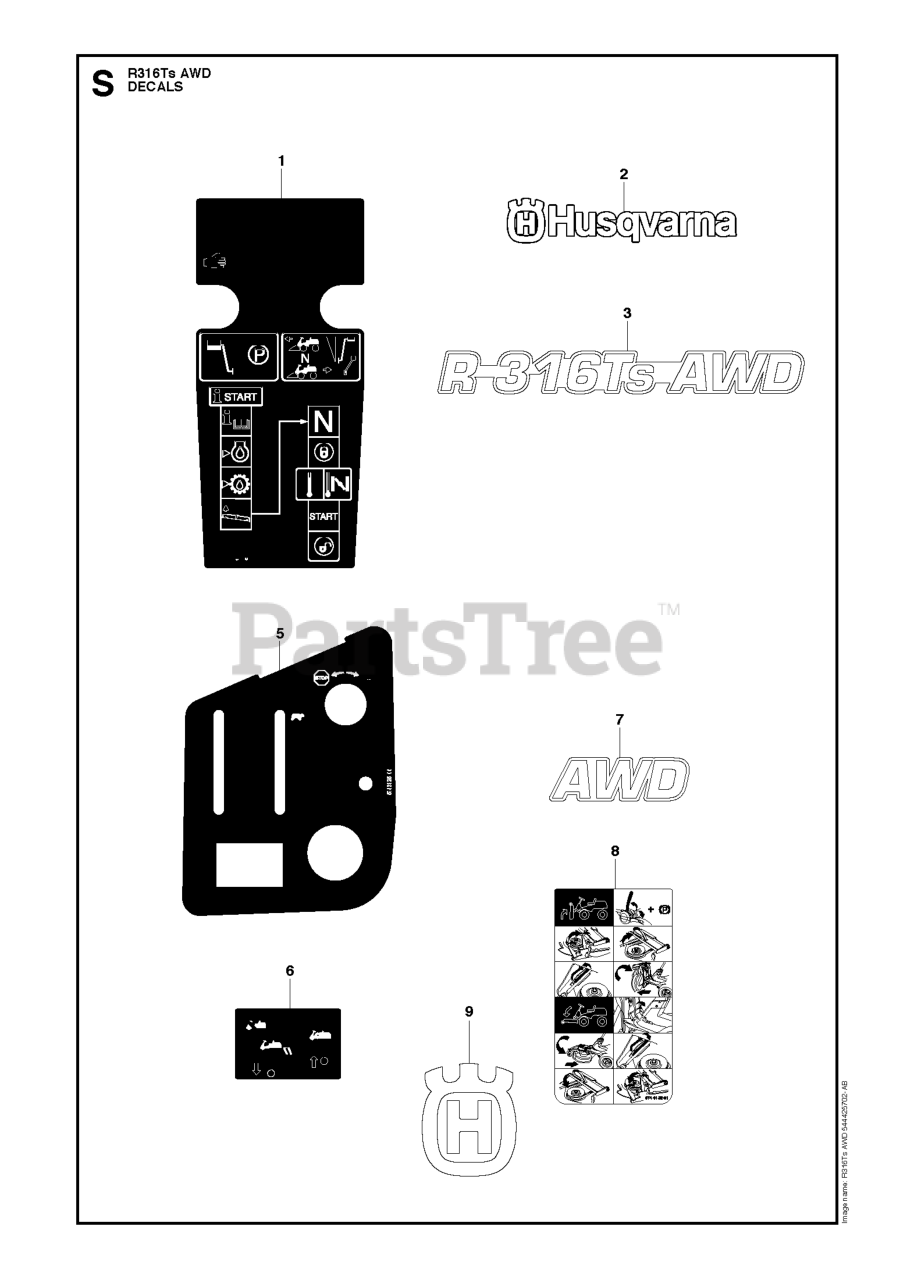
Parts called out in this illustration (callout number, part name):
1	CRANKCASE-C
2	GASKET CASE
5	SEAL
7	BOLT
8	COVER, CASE
9	BOLT 08
10	PISTON
16	CRANKSHAFT C
17	KEY
